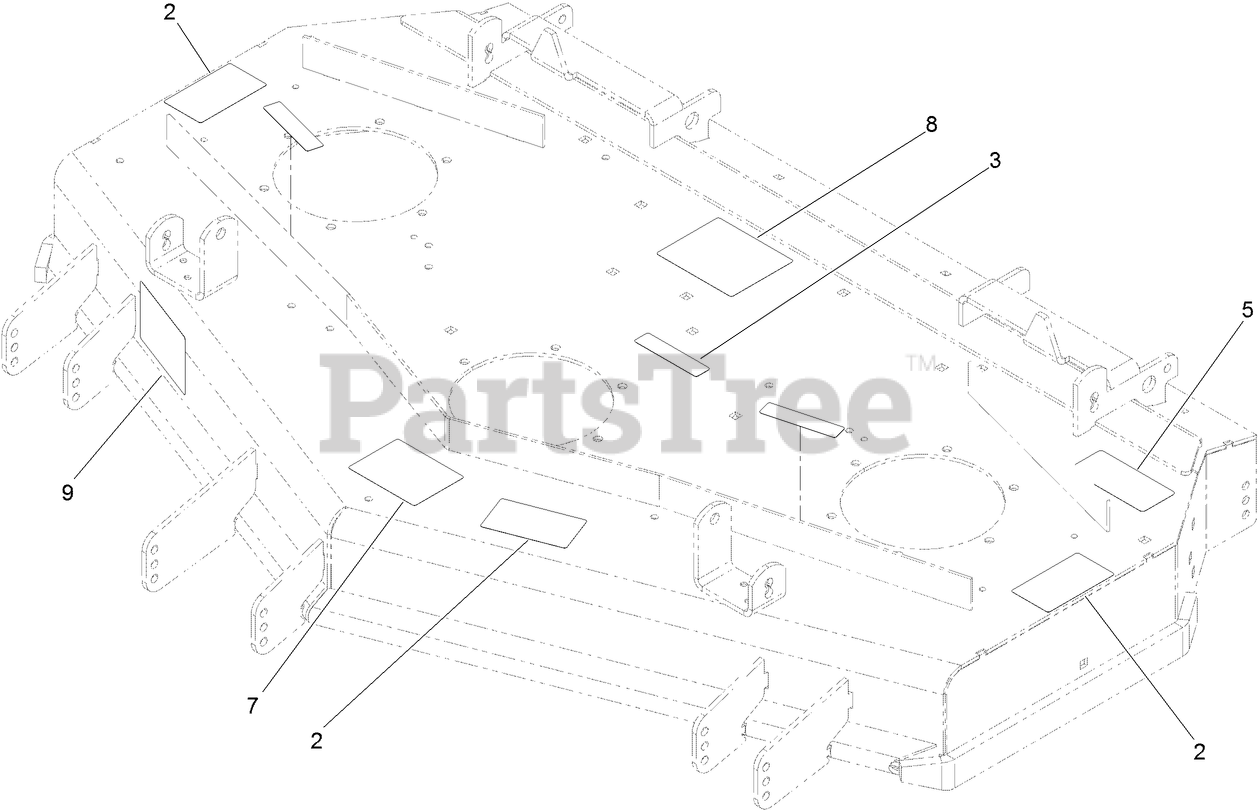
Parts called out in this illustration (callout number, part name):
2	DECAL-DANGER
3	DECAL-WARNING
5	DECAL-TORQUE, BLADE BOLT
7	DECAL-SCALP, ANTI
8	DECAL-ROUTING, BELT
